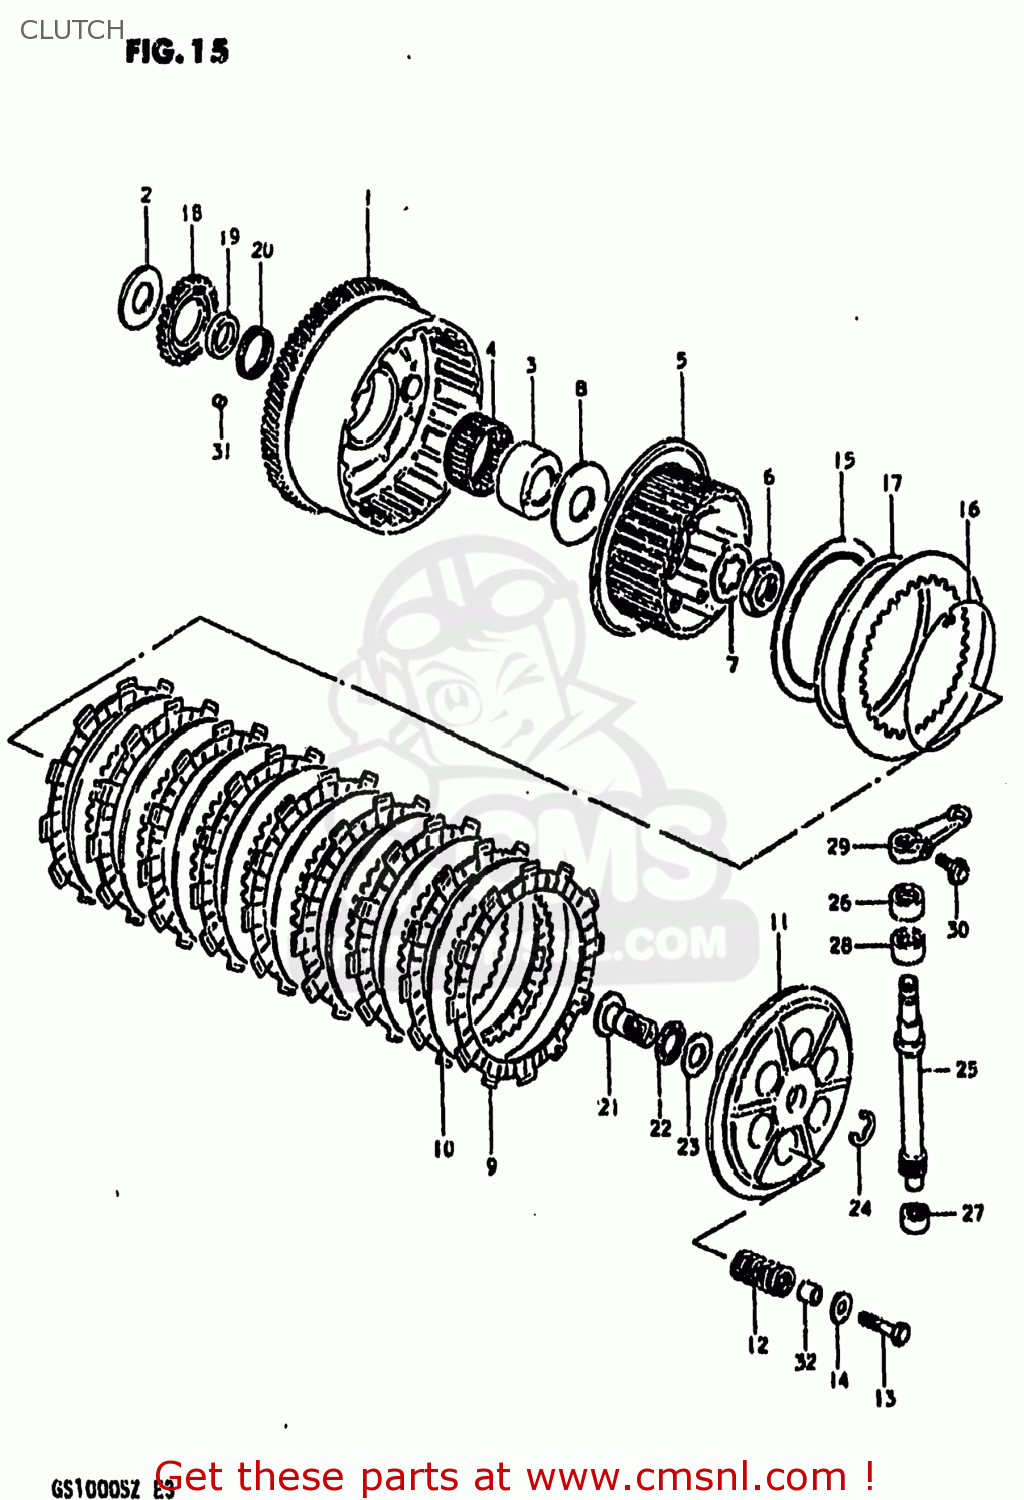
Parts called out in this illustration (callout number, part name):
1	GEAR ASSEMBLY,PRIMARY DRIVE
2	WASHER
3	SPACER
4	BEARING
5	HUB,CLUTCH SLEEVE
6	NUT
7	WASHER,LOCK
8	WASHER(25X66X3.5)
9	PLATE,CLUTCH DRIVE (MCA)
10	PLATE,CLUTCH DRIVEN (NAS)
11	DISC,CLUTCH PRESSURE
12	SPRING
13	BOLT
14	WASHER
15	SEAT,WAVE WASHER
16	RING,STOPPER
17	WASHER
18	GEAR,OIL PUMP DRIVE
19	SPACER,OIL PUMP DRIVE GEAR
20	BEARING(36X40X10)
21	RACK,CLUTCH RELEASE
22	BEARING(15X28X2)
23	WASHER
24	E RING 12MM
25	PINION,CLUTCH RELEASE
26	OIL SEAL
27	BEARING(12X19X12)
28	BEARING(15X22X12)
29	ARM,CLUTCH RELEASE
30	BOLT,REAR
31	CUSHION,PRIMARY DRIVEN GEAR
32	SPACER
